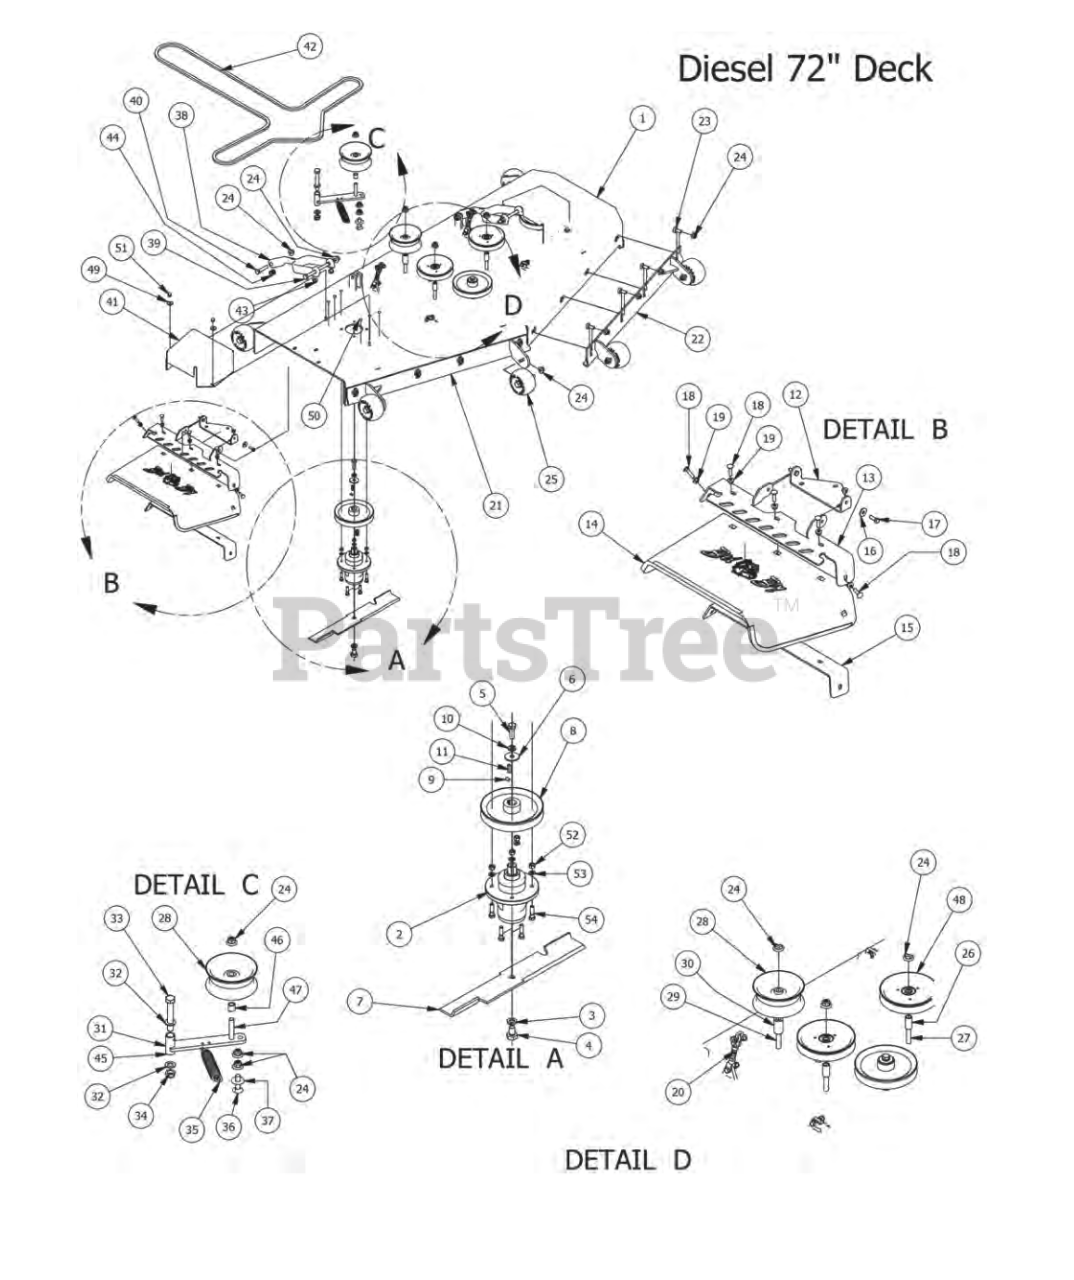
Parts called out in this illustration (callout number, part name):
1	72" (Deck Only)
2	Double Bearing Spindle
3	5/8" Lock Washer
4	5/8" x 1 1/2" Gr8 Hex Bolt (Fine)
5	1/2"-20 x 1 1/2 - Grade 5 Fine Thread Bolt
6	1/2 Belleville Washer
7	72" High Lift Fusion Blade
8	7" Deck Pulley
9	5/16 Set Screw
10	1/2" Lock Washer
11	1/4" x 1" Key
12	Discharge Chute Hanger (deck mounted)
13	60" Upper Discharge Chute Bracket
14	Rubber Discharge Chute
15	60" Lower Discharge Bracket
16	.360 ID Plastic Washer
17	5/16" x 1" Bolt
18	5/16" x 1 1/4" Carriage Bolt
20	5-Link Adjustable Deck Hange
21	72" Deck Adustable Front (Right)
22	72" Deck Adjustable Front (Left)
23	1/2" x 1 1/4 Carriage Bolt
24	1/2-13 Nylon Insert Flange Nut
25	Anti-Scalp Rollers
26	502 ID X.75 OD X 1.500 Leng
27	1/2 x 3 1/2 Flange Bolt Grade 8
28	5 3/4" Deck Idler Pulley
29	1/2" x 4" Bolt (Grade 8)
30	1 3/4" Pulley Spacer
31	Deck Idler
32	.635 ID Plastic Washer
33	5/8" x 4" Hex Bolt
34	5/8-11 Nylon Insert Jam Half Nut
35	2009 Deck/Pump Idler Spring
36	1/2 x 2" Carriage Bolt
37	517 Square Hole Round Washer
38	Deck Arm Assembly
39	1/2" x 5 1/2" Bolt
40	1/2-13X 2-1/4 GR Hex Bolts
41	72 Spindle Cover
42	B252-50 Fits 2007 72" Diesel
43	Flange Bushing For Deck Arm upper
44	Flange for Lower Deck Arm
45	Deck Idler Complete Assembly- Componets 29,34,37,57,58
46	3/4 OD x 1/2 ID x 3\4 Length
47	1/2-13 x GR 5 Hex Bolt Zinc
48	5-3/4 Idler Pulley
49	360 ID Plastic Washer-Black
50	Black, Round Stick-On Rubber Bumpon
51	Acorn nut-pulley Cover
52	3/8" Hex Nut
53	3/8" Lock Washer
54	3/8" x 1 1/2" Hex Bolt
